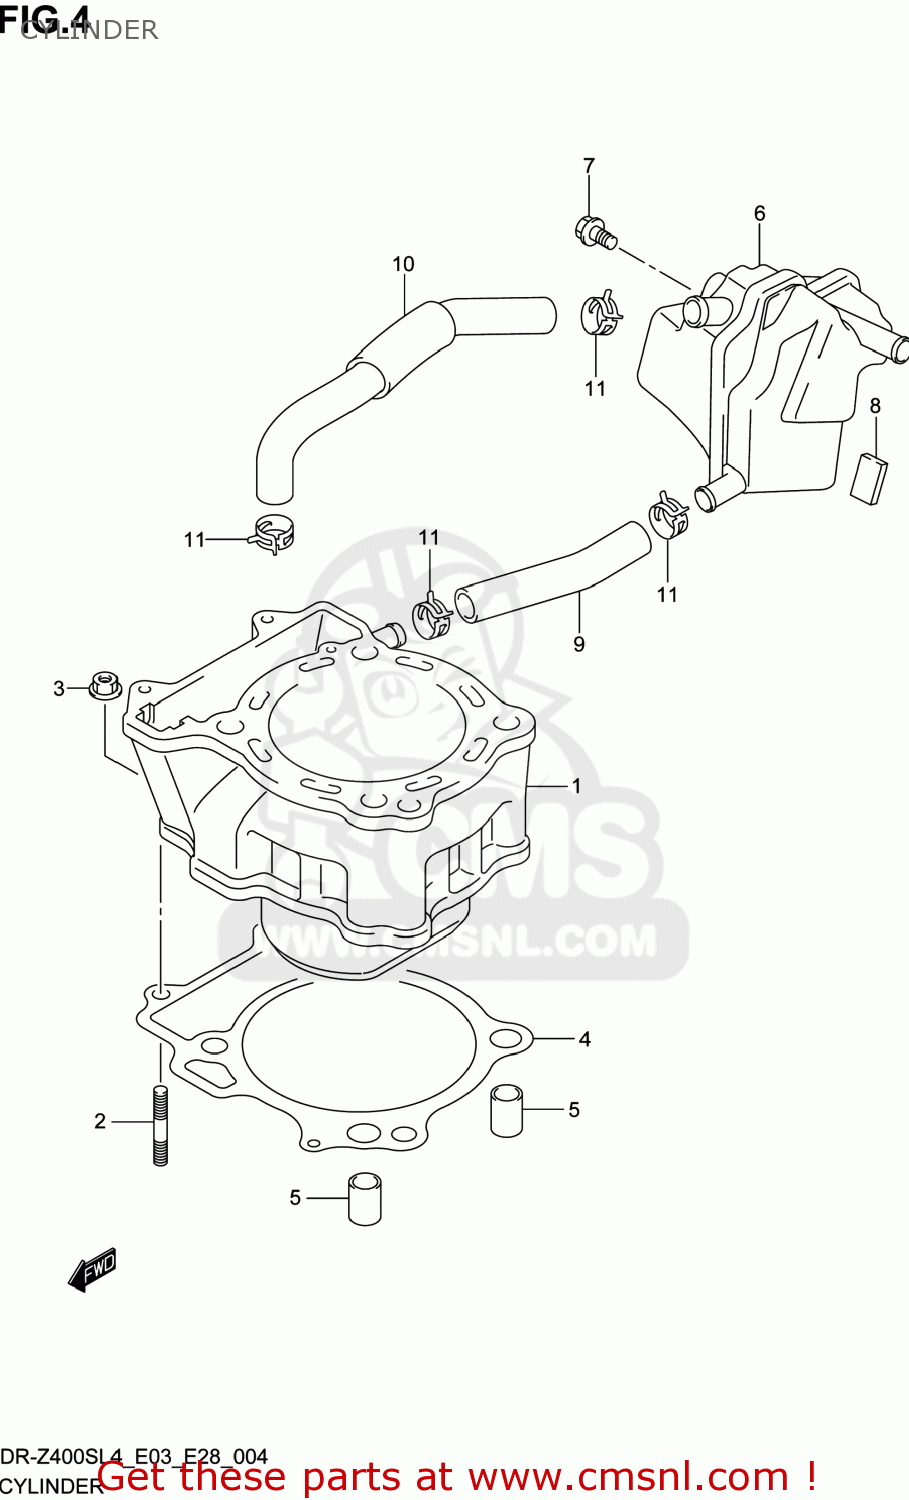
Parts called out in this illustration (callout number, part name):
1	CYLINDER
2	BOLT,STUD
3	NUT
4	GASKET,CYLINDER (NAS)
5	PIN
6	TANK,OIL RETURN
7	BOLT
8	PROTECTOR(170X95X3.0)
9	HOSE,BREATHER
10	HOSE,BREATHER
11	CLIP
